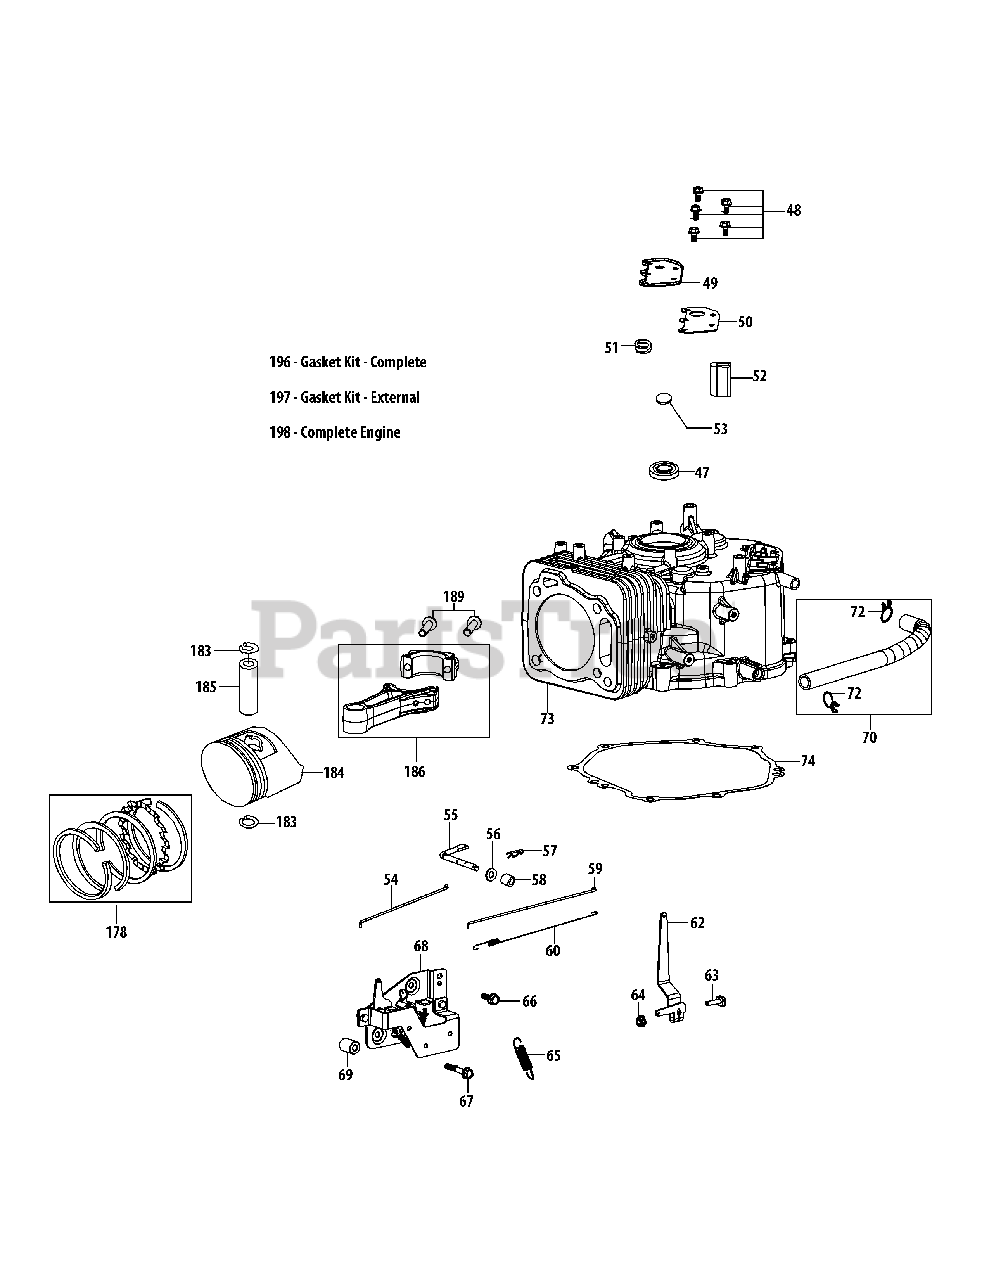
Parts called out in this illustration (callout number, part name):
47	Upper Crankshaft Seal
48	Bolt M6×14
49	Breather Cover Plate
50	Breather Gasket
51	Umbrella Valve
52	Mesh Screen
53	Umbrella Valve Seat
54	Choke Linkage
55	Governor Arm Shaft
56	Governor Washer
57	Governor Cotter Pin
58	Governor Seal
59	Throttle Linkage
60	Throttle Linkage Spring
62	Governor Arm
63	Governor Arm Bolt
64	Governor Arm Nut M6
65	Governor Spring
66	Bolt M6×18
67	Bolt M6×38
68	Component Bracket/Separate
69	Component Bracket Spacer
70	Breather Hose Assembly
72	Breather Hose Clamp
73	Short Block Assembly
74	Crankcase Cover Gasket
178	Piston Ring Set
183	Piston Pin Snap Ring
185	Piston Pin
186	Connecting Rod Assembly
189	Connecting Rod Bolt
196	Gasket Kit - Complete
197	Gasket Kit - External
198	Complete Engine
